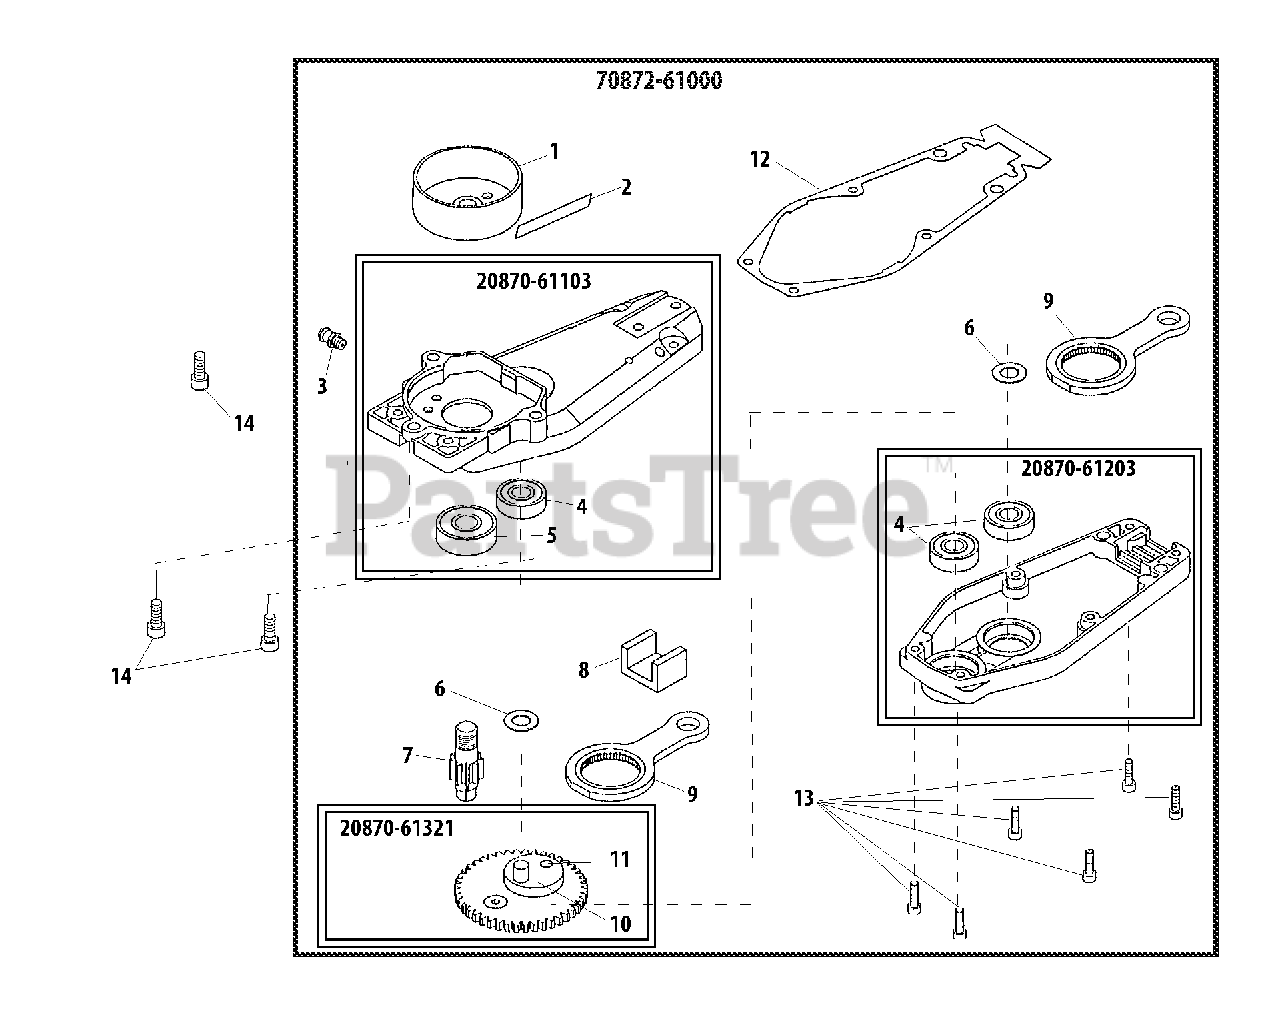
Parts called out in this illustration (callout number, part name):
1	DRUM, CLUTCH
2	LABEL - LUBRICATION
3	FITTING, GREASE
4	BEARING, BALL - 6000
5	BEARING, BALL - 6201
6	SPACER, PISTON
7	GEAR - SHAFT
8	SEAL, FELT
9	ROD, CONNECTING
10	GEAR - SPUR
11	BOLT
12	GASKET, GEAR CASE
13	BOLT
14	SCREW - 6X16
20870-61103	GEAR CASE ASSY - UPPER
20870-61203	GEAR CASE ASSY - LOWER
70872-61000	GEAR CASE ASSY
